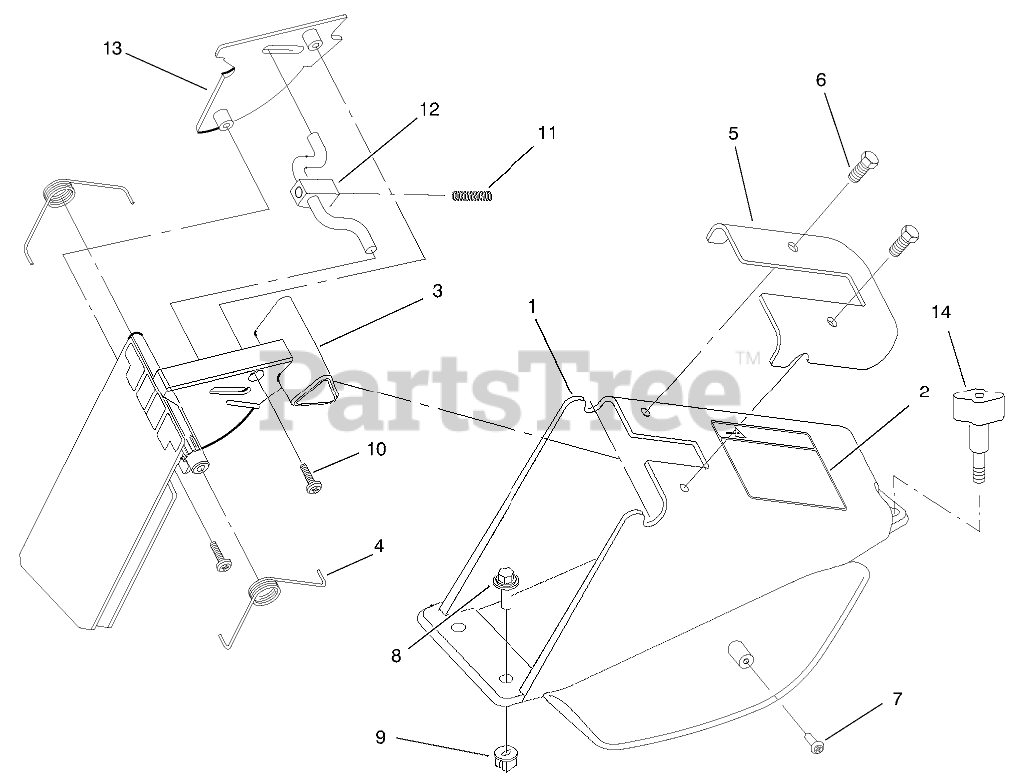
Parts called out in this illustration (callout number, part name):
1	Chute-Discharge (Incl. Ref #2)
2	DECAL - CAUTION DOOR
3	DOOR-DISCHARGE
4	SPRING-DOOR, RH
5	Plate-Discharge
6	SCREW-PLASTITE
7	SCREW-PPH
8	SCREW-HWH
9	NUT - CLIP
11	SPRING-COMPRESSION, LATCH
12	LATCH-DOOR
13	DOOR COVER
